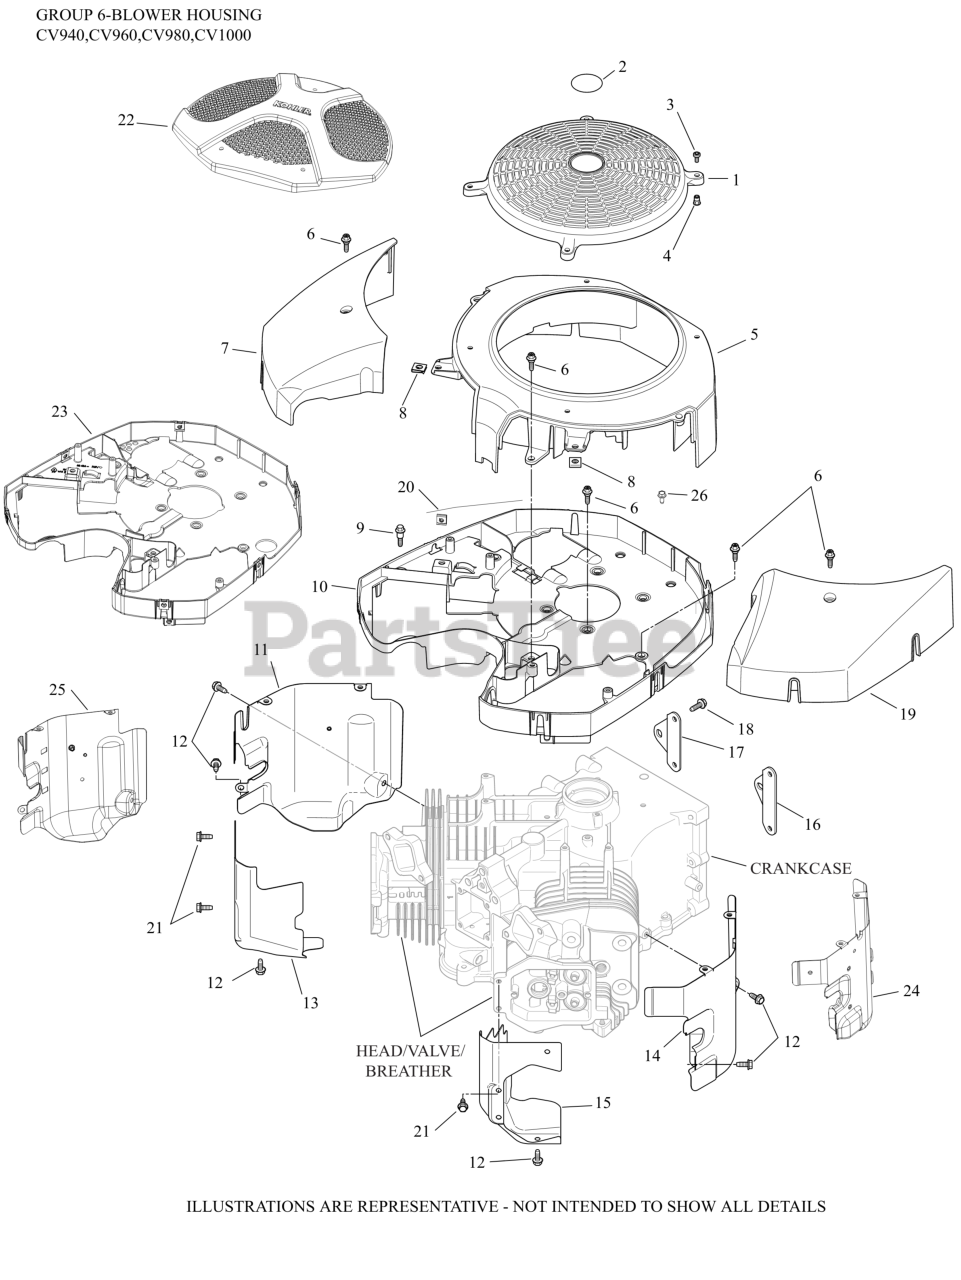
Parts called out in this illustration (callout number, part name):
1	KIT, FIXED GUARD
3	SCREW, LBD SCKT PAN M5X0.8X10
4	INSERT, THREADED (M5)
5	HOUSING, BLOWER-USE 62 027 07-S
6	SCREW, SHD THD FRM
7	SHROUD, #1 CYLINDER
8	CLIP, BAFFLE MOUNTING
9	SCREW, SHD THD FRM M6X1X26
13	BAFFLE, VALLEY #1 SIDE
14	BAFFLE CYL BARREL #2 SIDE
15	BAFFLE VALLEY #2 SIDE
16	STRAP, LIFTING
19	SHROUD, #2 CYLINDER-USE 62 424 13-S
21	SCREW, THREAD FORMING
23	SHROUD AND CLIP ASSEMBLY
25	BAFFLE, BARREL (#1 CYL)
